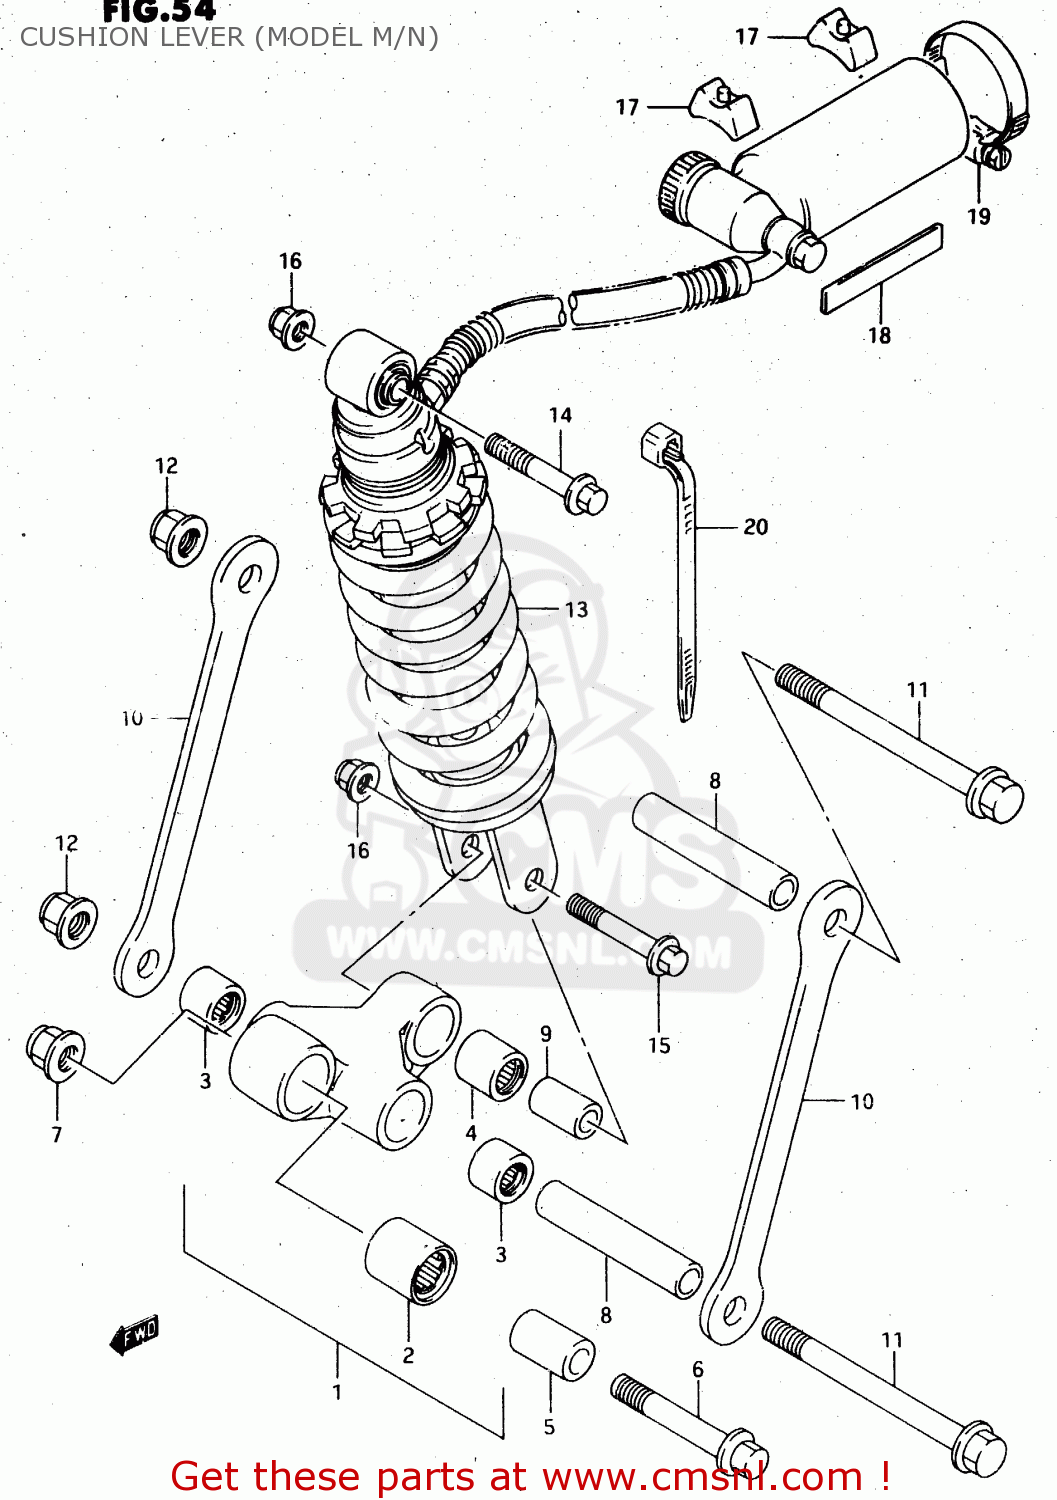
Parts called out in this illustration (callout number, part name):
1	LEVER SET,RR CUSHION
2	BEARING(20X27X30)
3	BEARING(17X24X20)
4	BEARING(17X24X26)
5	SPACER,RR CUSHION LEVER FR
6	BOLT,RR CUSHION LEVER FR
7	NUT 12MM
8	SPACER(12X17X85)
9	SPACER,RR CUSHION LEVER
10	ROD, REAR CUSHION LEVER
11	BOLT(12X115)
12	NUT 12MM
13	ABSORBER ASSY, REAR SHOCK
14	BOLT(10X75)
15	BOLT(10X54)
16	NUT
17	CUSHION,RESERVOIR TANK
18	CUSHION, RESERVOIR TANK
19	CLAMP
20	CLAMP(L:125)
